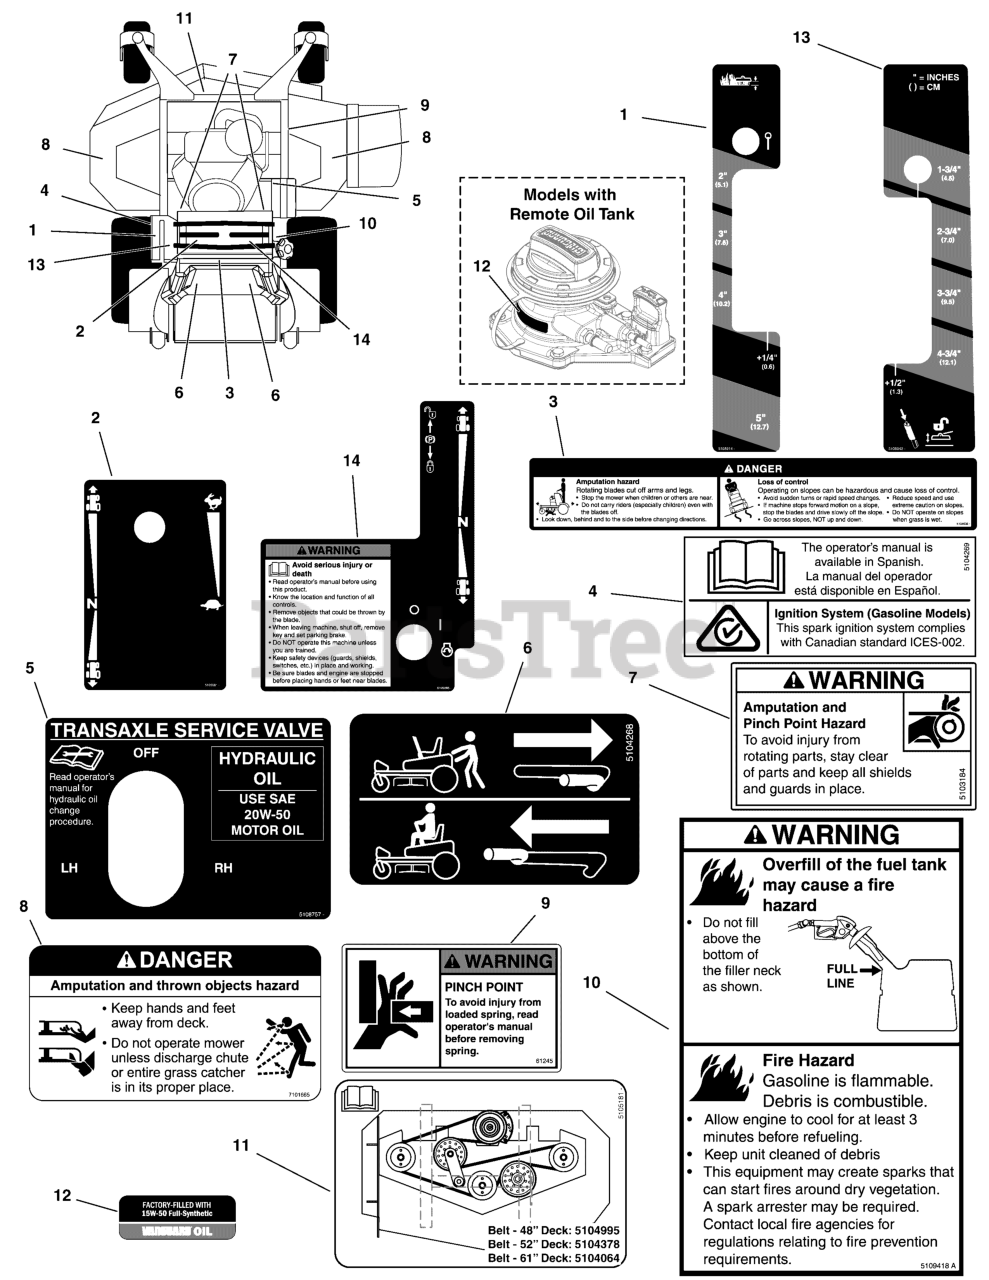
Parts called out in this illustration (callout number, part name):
1	DECAL, CUT HEIGHT, SRSZ2 & Z3
2	DECAL, DASH PANEL, LH, CONTROLS
3	DECAL, Danger
4	DECAL, SPANISH MANUAL, IGES, C-TICK
5	DECAL, TRANSAXLE SELECTOR VALVE
6	DECAL, TRANSAXLE RELEASE, WB
7	DECAL, WARNING, HAND IN BELT, ENG ONLY
8	DECAL, DANGER DO NOT OPERATE W/O DEFLECT
9	DECAL, Pinch Point
10	DECAL, WARNING, TANK OVERFILL
11	DECAL, BELT ROUTING, SRS-48-52-61
12	LABEL, OIL INFORMATION
13	DECAL, CUT HEIGHT, STAND ON
14	DECAL, DASH PANEL, RH, WARNING/CONTROLS
